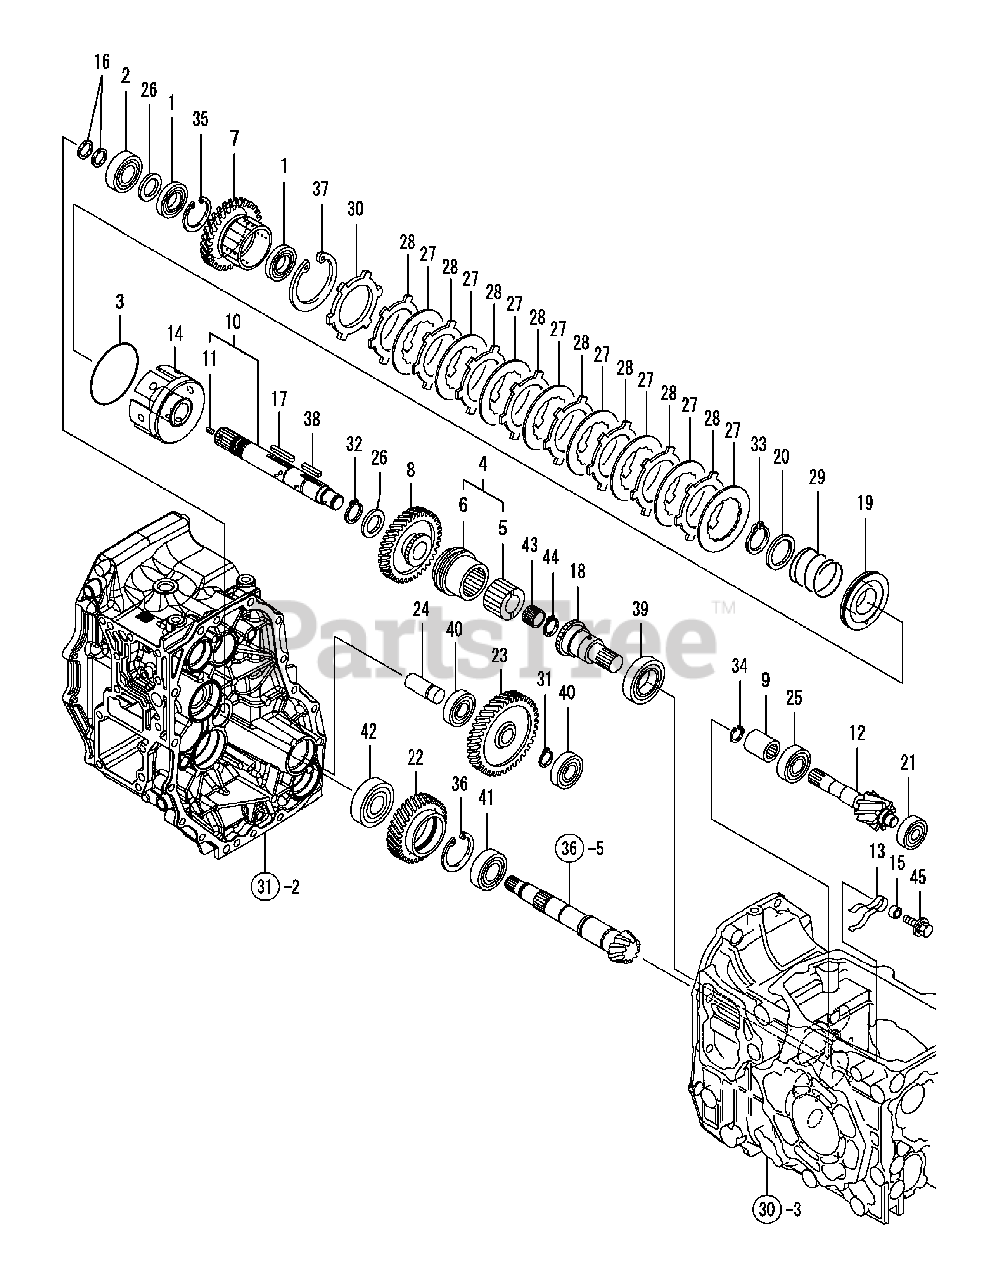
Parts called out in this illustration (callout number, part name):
1	Bearing 16005, Ball
4	Collar Set,Spl PTO
5	Spline Collar, PTO
7	Gear(Clutch 33T
10	Shaft Assy, Clutch
12	Gear, Pto Z=10T
14	Cylinder, Clutch
15	Collar 15Xt2.5
16	Ring, 21X25X3 Seal
18	Shaft,PTO Drive Out
20	Washer, 36X48X2
21	Bearing Tmb302
22	Gear(Pto Idle Z=35
23	Gear, Pto Idle Z=45
24	Shaft, Idle Mid
25	Bearing,6204R Sh2
26	Thrust Washer (C)
27	Plate 80,Friction
28	Plate 1.2,Steel
29	Spring,Clutch Return
30	Plate 3.2, Steel
40	Ball Bearing #6204
